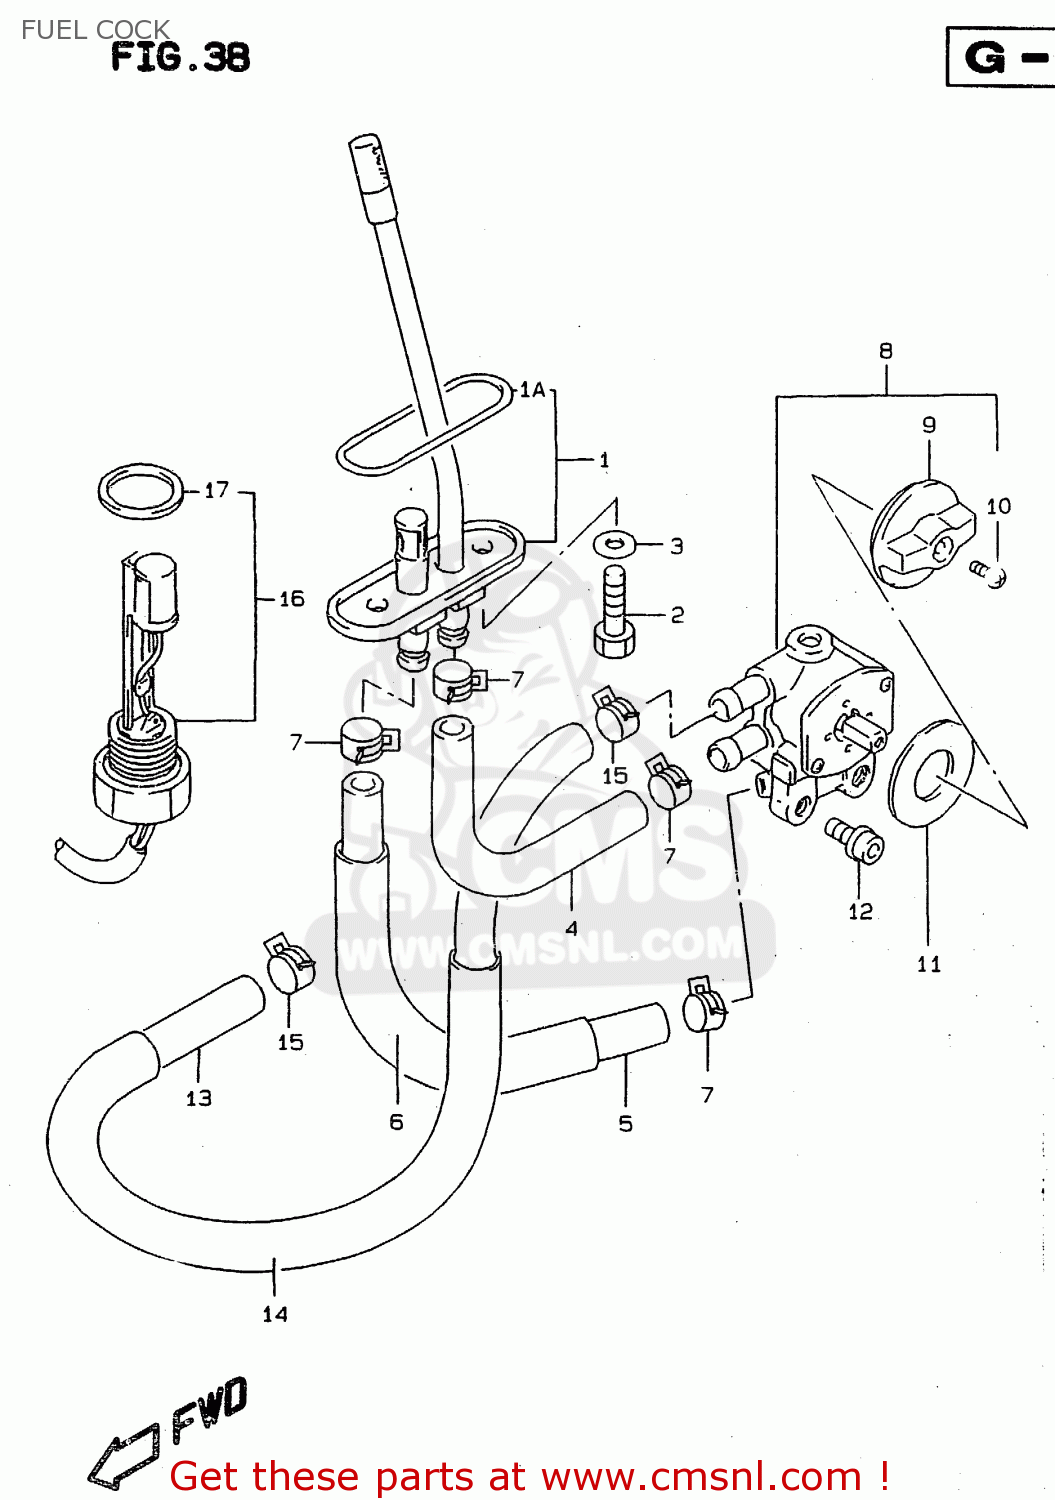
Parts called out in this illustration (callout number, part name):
1	FILTER,FUEL
1A	O RING
2	BOLT(6X20)
3	GASKET(6.4X11.5X0.8) (NAS)
4	HOSE,FUEL ON
5	HOSE(7X12X600)
6	PROTECTOR(14.5X15.5X600)
7	CLIP
8	COCK ASSY,FUEL
9	LEVER,FUEL COCK
10	SCREW
11	COVER,FUEL COCK
12	SCREW 6X12
13	HOSE(7X12X600)
14	PROTECTOR(14.5X15.5X600)
15	CLIP
16	GAUGE ASSY,FUEL LEVEL
17	GASKET,FUEL LEVEL GAUGE (NAS)
